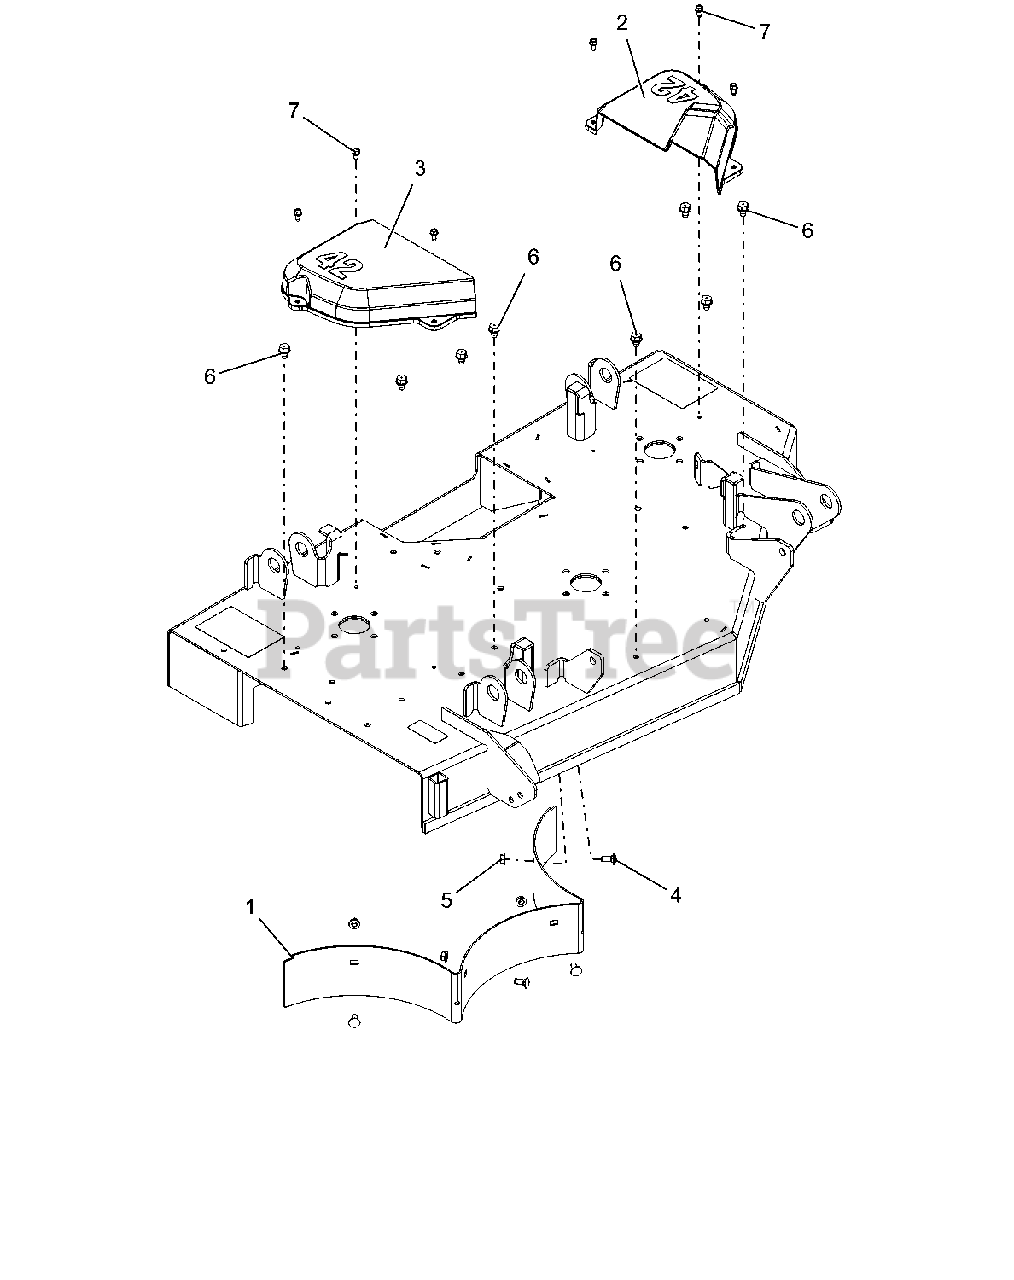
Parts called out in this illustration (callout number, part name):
1	BAFFLE, REAR 42"-RED
2	COVER, BELT 42" LEFT
3	COVER, BELT 42" RIGHT
4	BLT-RDHDSQNK .31-18X.75 G5 YWZC
5	NUT, LK-TOP-FLG .312-18 YWZC
6	SCR-TAP .38-16X.50 HWH TR YWZ
7	SCR-TAP .25-20X.50 HWH TR YWZ
